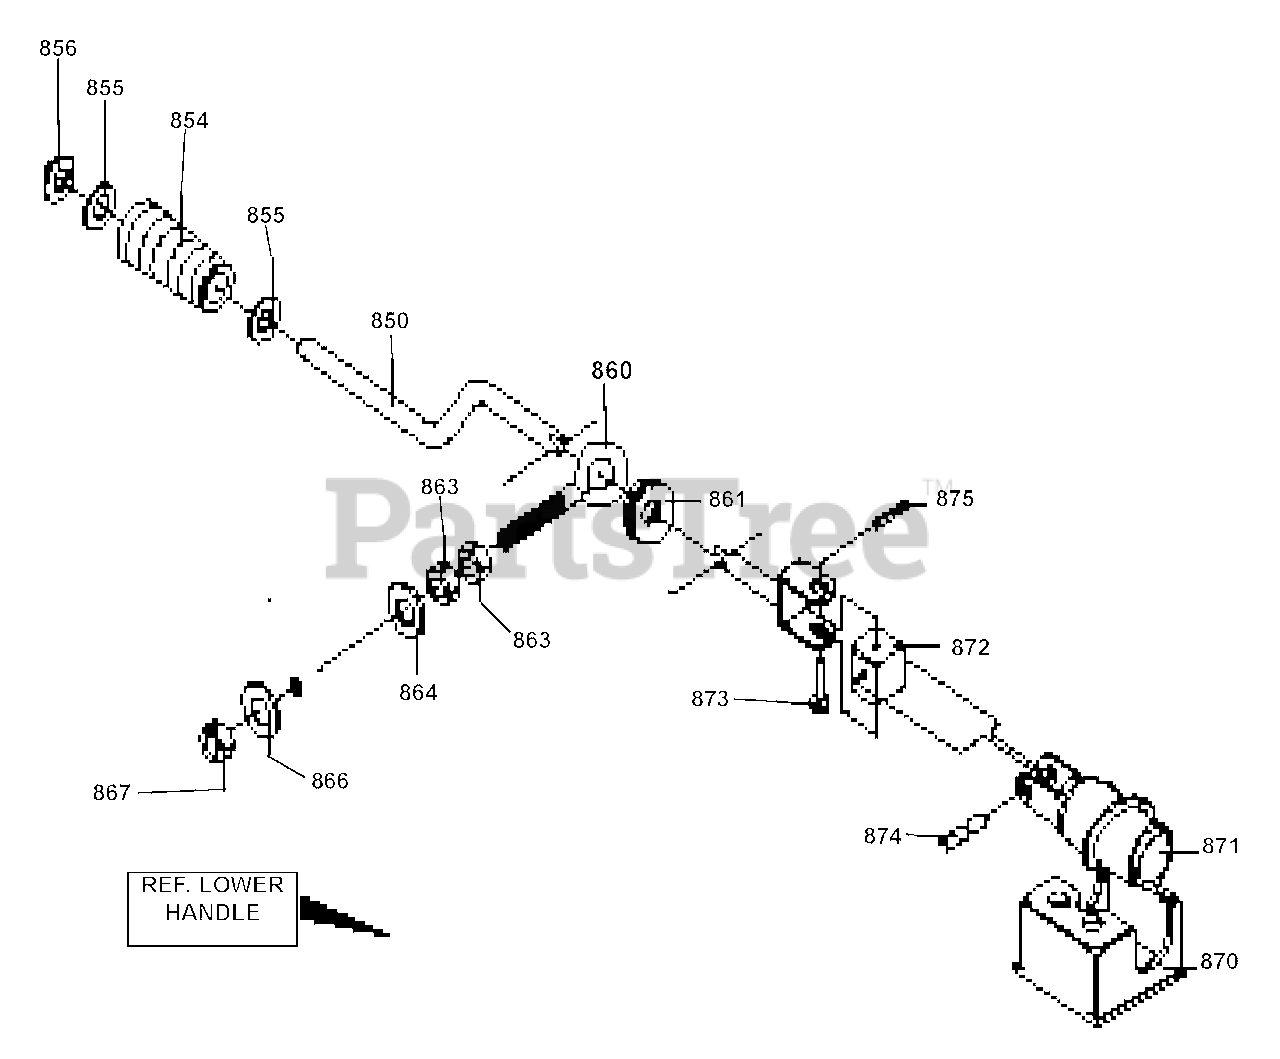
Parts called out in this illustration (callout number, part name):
850	CRANK, ASSY W/YOKE
854	KNOB, SLEEVE
855	WASHER, FLAT
856	NUT, PUSH ON 3/8"
860	BOLT, EYE 6"
861	GROMMET, EYE BOLT
863	NUT, 3/8-16 HEXJAM
864	WASHER, FLAT .406X.81X.065
866	WASHER, FLAT .406X .81X.065
867	NUT, 3/8-16
870	BRACKET, WORM
871	WORM, GEAR CHUTE
872	BLOCK, UNIVERSAL
873	PIN, CLEVIS
874	PIN, UNIV JOINT
875	PIN, COTTER .06X .50
